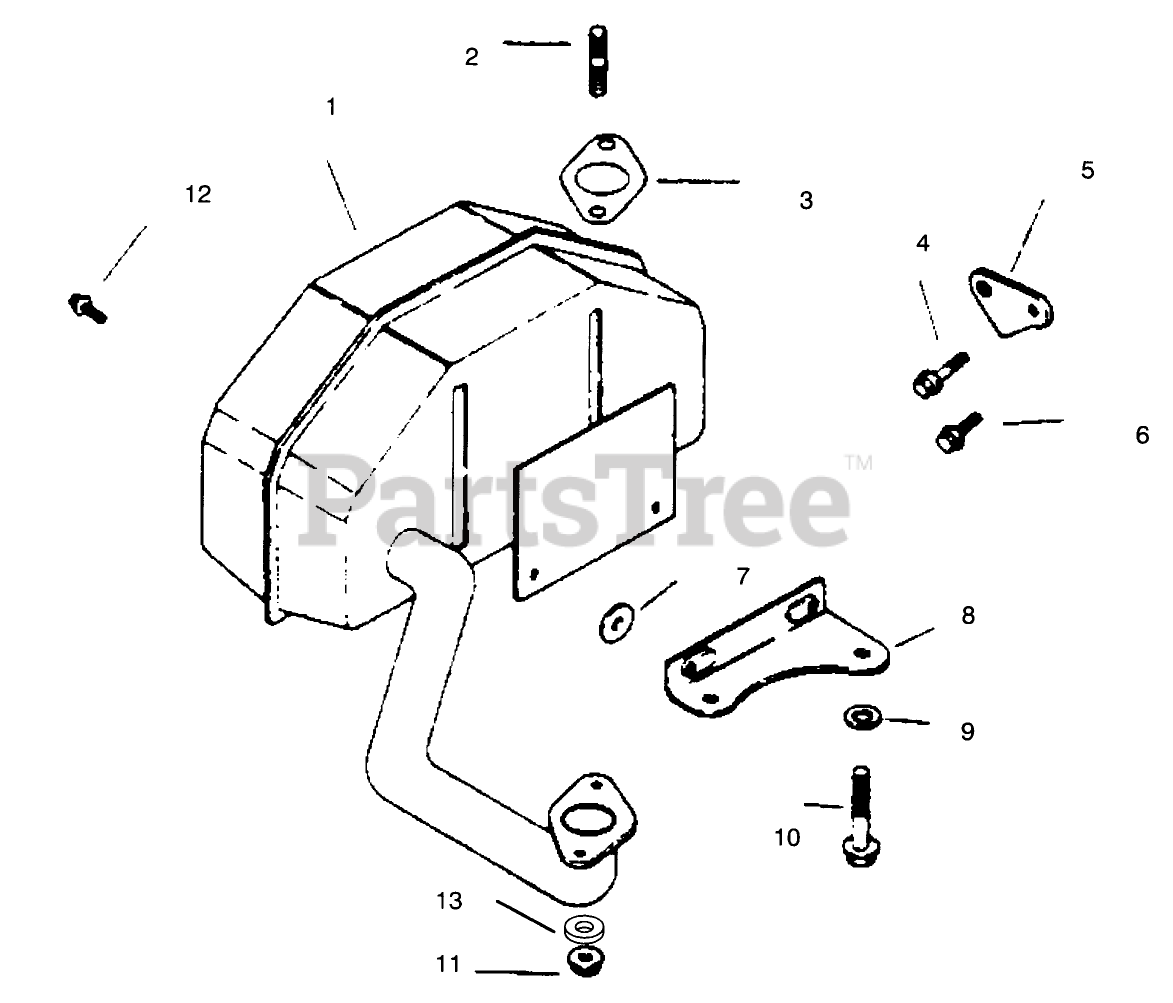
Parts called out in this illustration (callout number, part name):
1	Muffler
2	Stud
3	Gasket-Exhaust
4	Screw
5	Strap-Lifting
6	Screw
7	Washer
8	Bracket-Muffler
9	Washer
10	Screw
11	Nut
12	Screw
13	WASHER-LOCK
